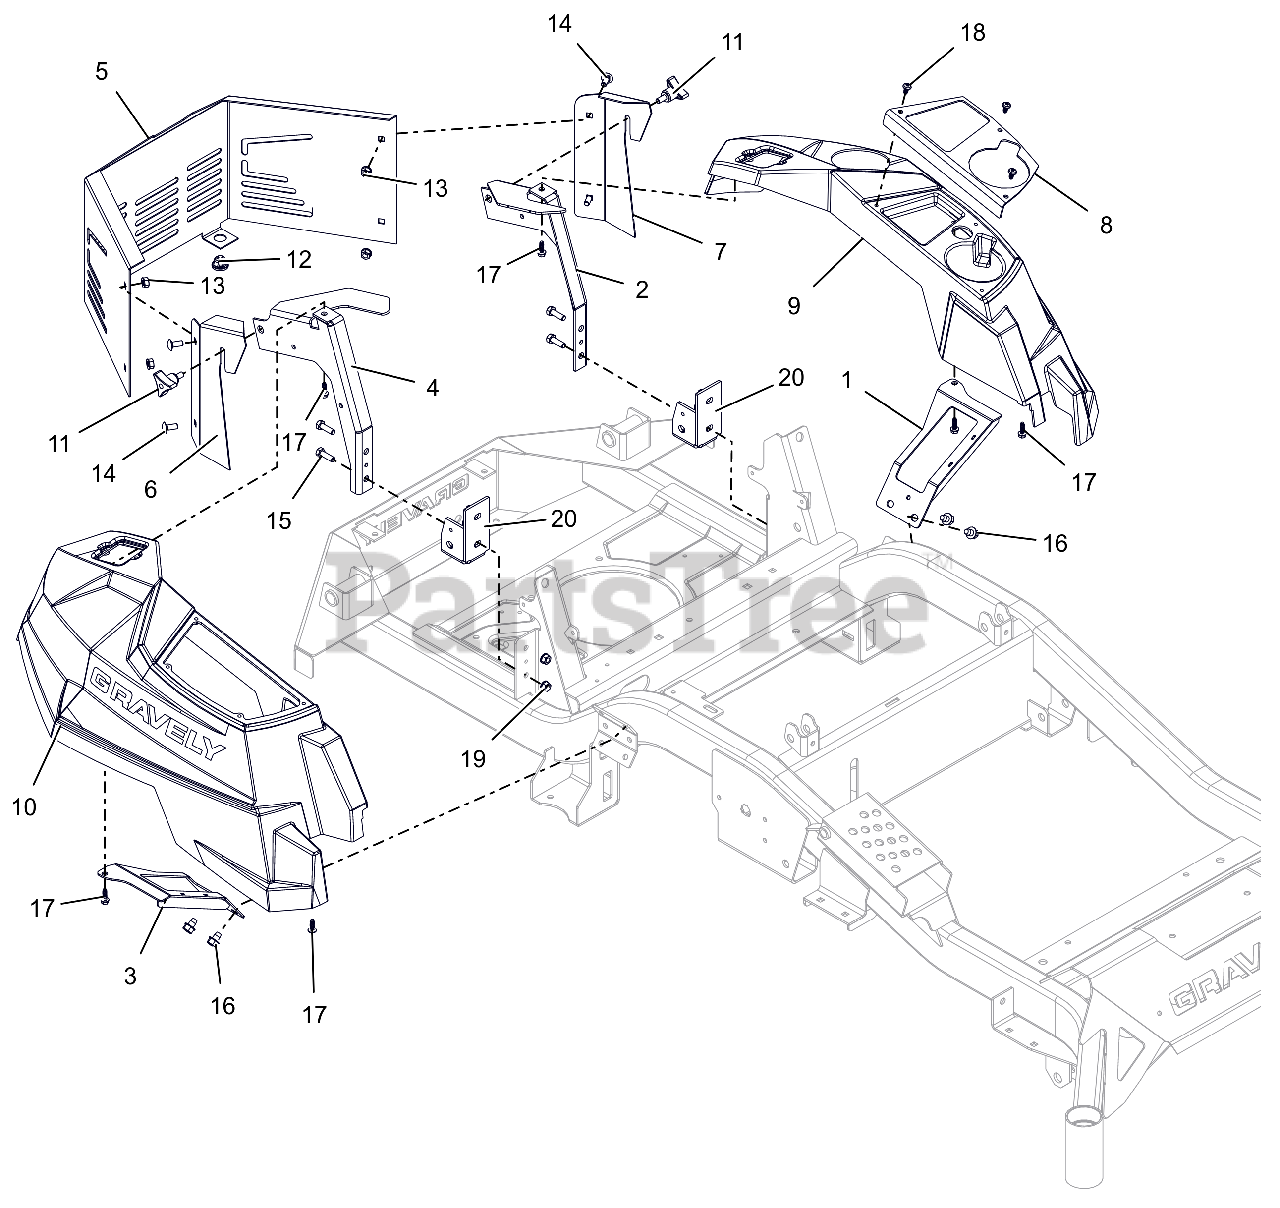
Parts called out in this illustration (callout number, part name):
1	WLDMT, LH FENDER MOUNT
2	BRKT, LH FENDER MTG
3	WLDMT, RH FENDER MOUNT
4	BRKT, RH FENDER MTG
5	GUARD, HD ENGINE
6	TRIM, HOOD STYLE (RIGHT)
7	TRIM, HOOD STYLE (LEFT)
8	PANEL, HD
9	KIT, FENDER W/FUEL DECAL-HD
10	FENDER, RH HD (2017) SHRT BOSS
11	KNOB,WING STUD 5/16-18 X .75
12	GROMMET, 10MM BOLLHOFF
13	NUT-LK-TOP-FLG .312-18 GF ZCC
14	BLT, RHSSN.31-18X.750 G5 ZCC
15	BLT, HEX .31-18X1.00 G8 ZCC
16	SCR,TAP .375-16X.50 HWH TR ZCC
17	SCR, PLASTITE-HWH 0.25 X 0.75 ZC120
18	SCR-PAN .25-15X.50 6L H/LZB500
19	NUT,LK-CTR-FLG .31-18 GF ZCC
20	BRKT, ROPS SUPPORT
